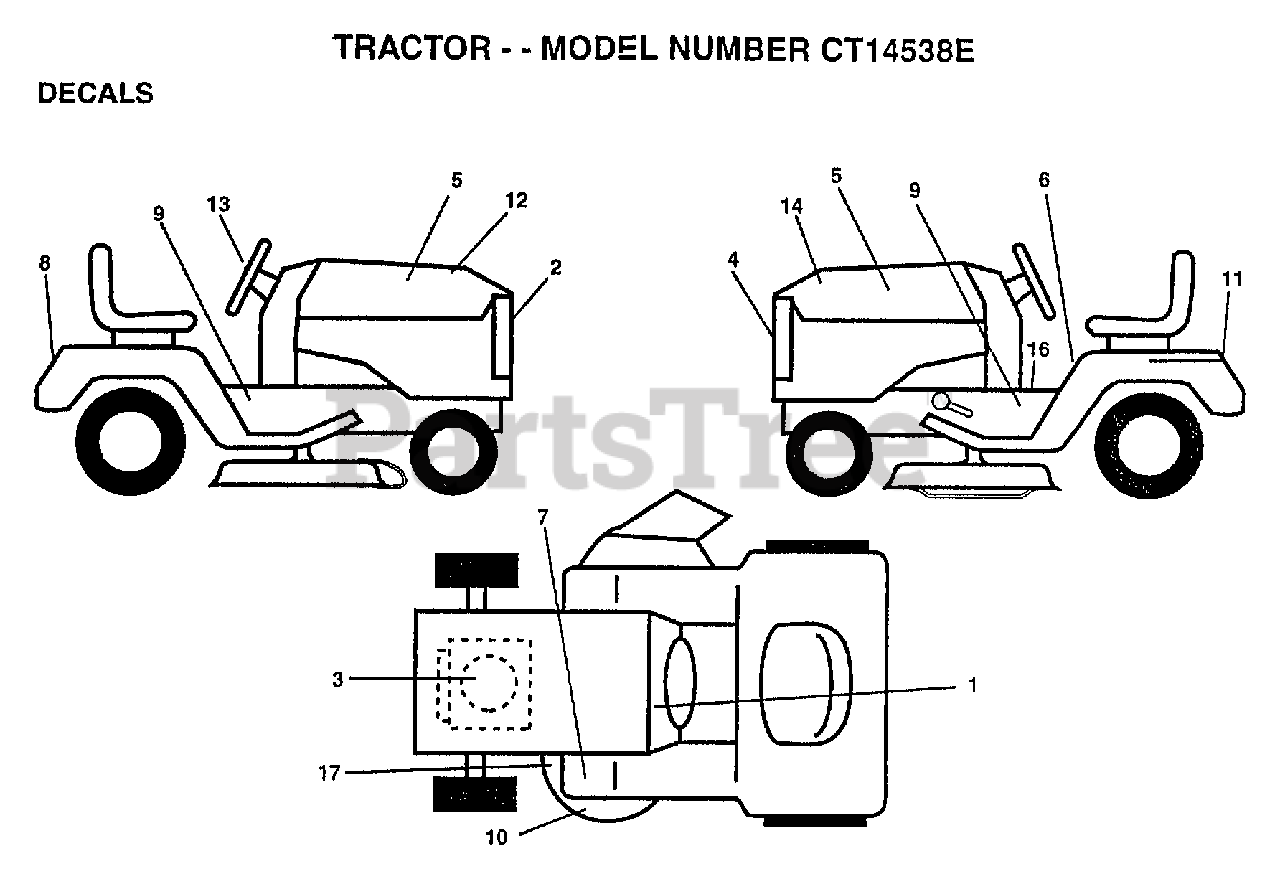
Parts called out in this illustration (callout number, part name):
1	"DECAL-OPER,GEAR D"
2	GRILL DECAL
3	DECAL, ENGINE
5	DECAL.INS.HD.RALL
6	"DECAL DANGER,FEND"
8	FENDER DECAL
11	DECAL.BATRY.3-3908
12	DECAL HOOD RH RLY
13	"DECAL,STR WHL"
14	DECAL HOOD LH RLY
16	DECAL BRAK PARK
17	DECAL
